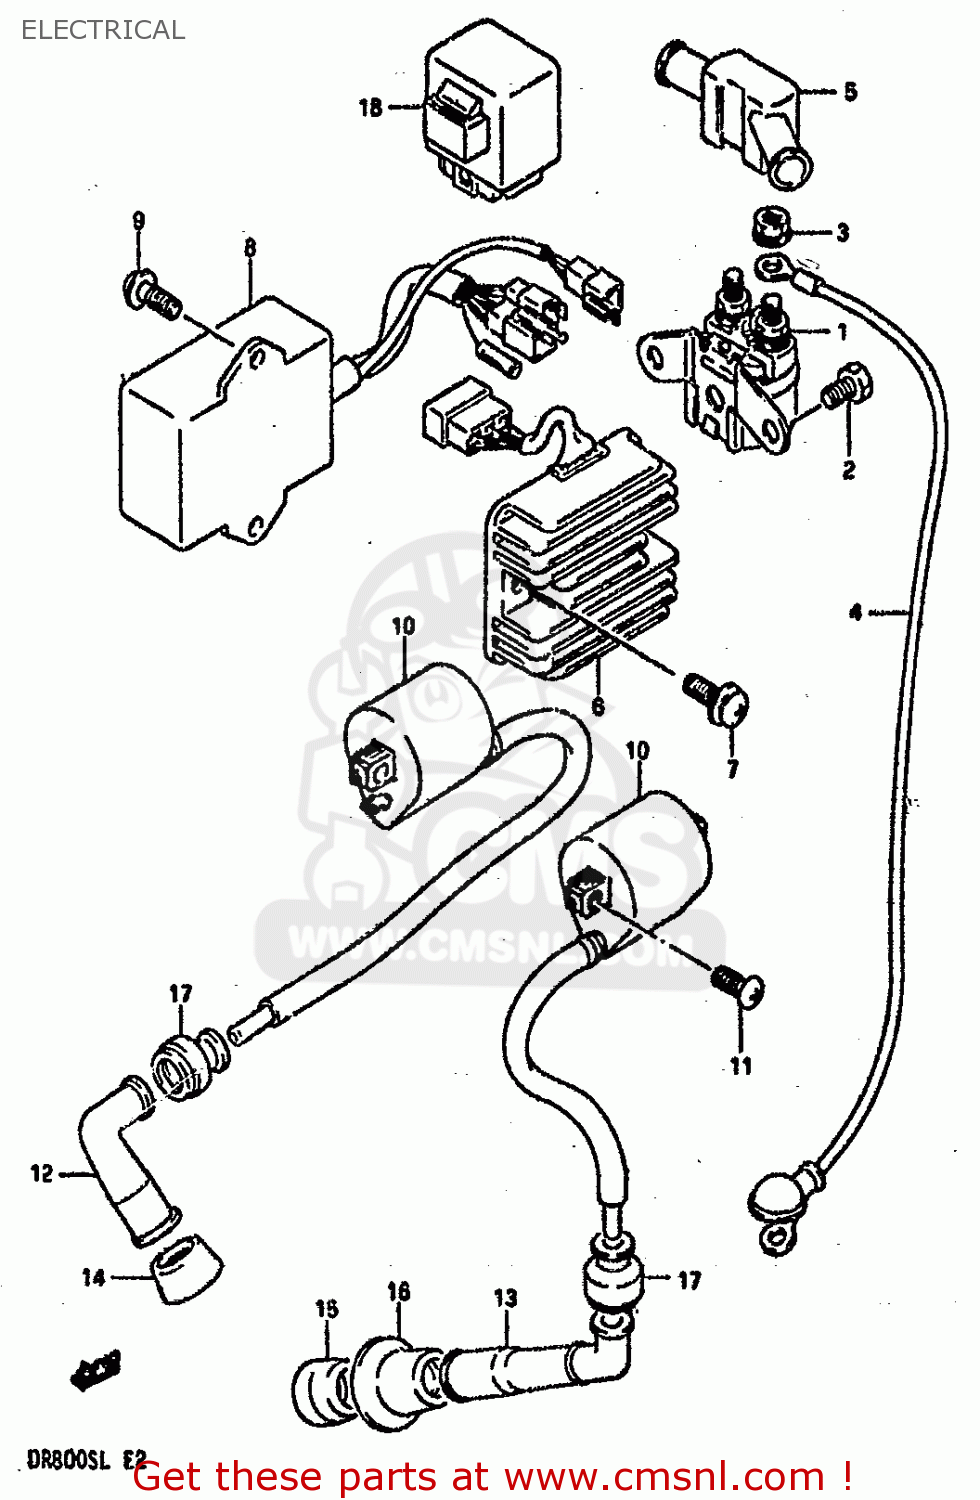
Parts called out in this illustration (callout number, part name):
1	RELAY ASSY,STARTING MOTOR
2	BOLT
3	NUT
4	WIRE,STARTING MOTOR
5	CAP,STARTER RELAY
6	RECTIFIER ASSY
7	SCREW
8	CDI UNIT
9	SCREW
10	COIL ASSY,IGNITION
11	SCREW
12	CAP,SPARK PLUG
13	CAP,SPARK PLUG
14	SEAL,SPARK PLUG CAP
15	SEAL,SPARK PLUG
16	COVER,SPARK PLUG CAP,L
17	SEAL,HIGH TENSION CORD
18	CONTROL UNIT,DECOMP
